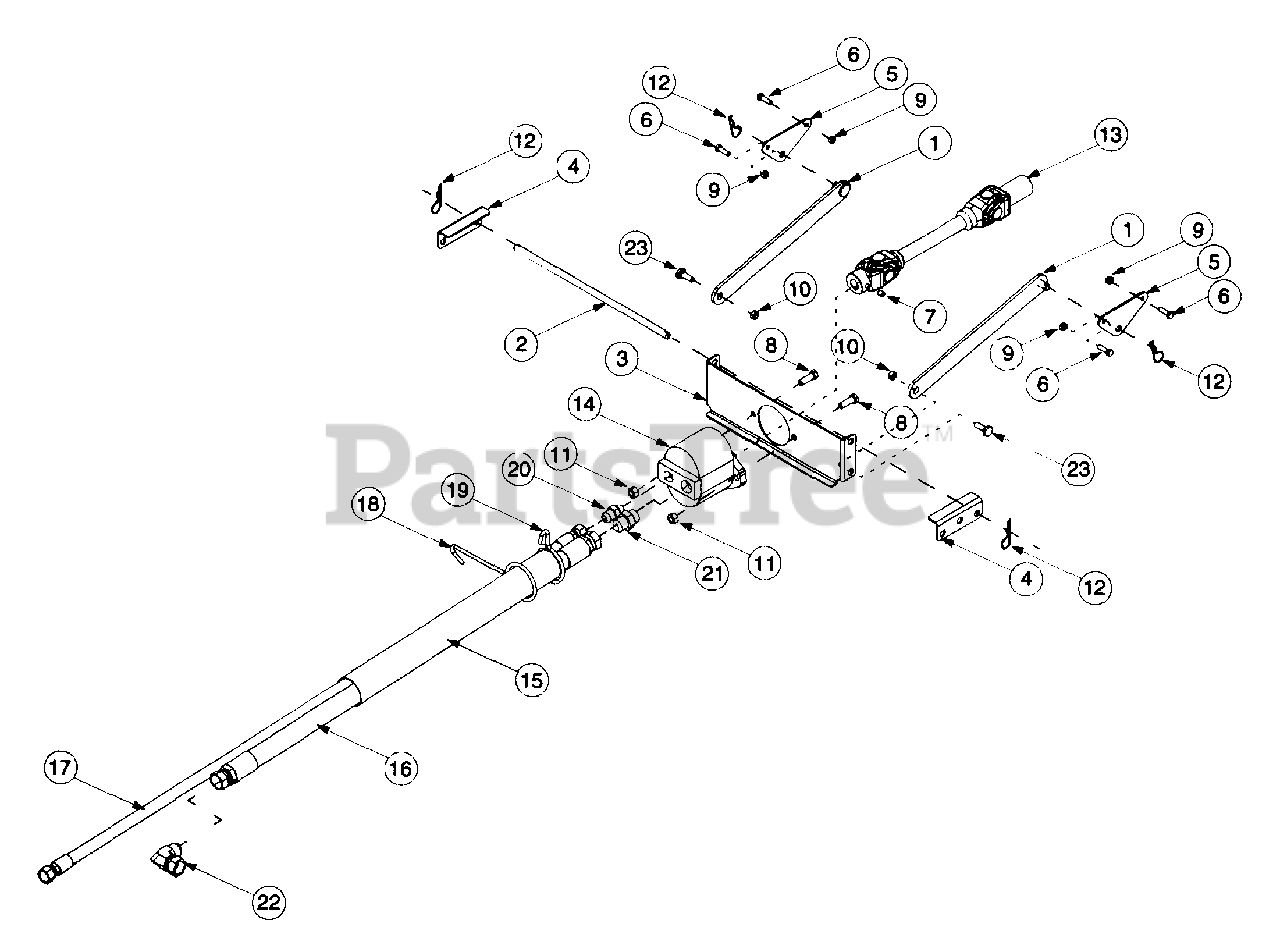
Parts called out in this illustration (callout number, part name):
1	Pump Support Brace
2	Hanger Rod
3	Pump Mounting Bracket
4	Rear Frame Bracket
5	Front Frame Bracket
6	Hex Cap Screw, 5/16-18 x 1.0
7	Set Screw, 3/8-16 x .437 Cup
8	Hex Cap Screw, 7/16-20 x 1.25
9	Hex Lock Nut, 5/16-18, Ctr Lock
10	Hex Lock Nut, 3/8-24, Top Lock
11	Hex Lock Nut, 7/16-20, Patch
12	Internal Cotter Pin
13	Hydraulic Pump Drive Shaft
14	Eaton Hyd. Pump (26012-LAP)
15	Hydraulic Hose Sleeve, 2.19 x 31
16	Hydraulic Hose, 1 1/16-12 x 56
17	Hydraulic Hose, 7/8-14 x 67
18	Long Support Hook
19	Short Support Hook
20	Hydraulic Fitting, 7/8
21	Hydraulic Fitting, 1 1/16
22	90° Hydraulic Fitting, 1 1/16
23	Shoulder Bolt, 1/2 Dia. x .180
